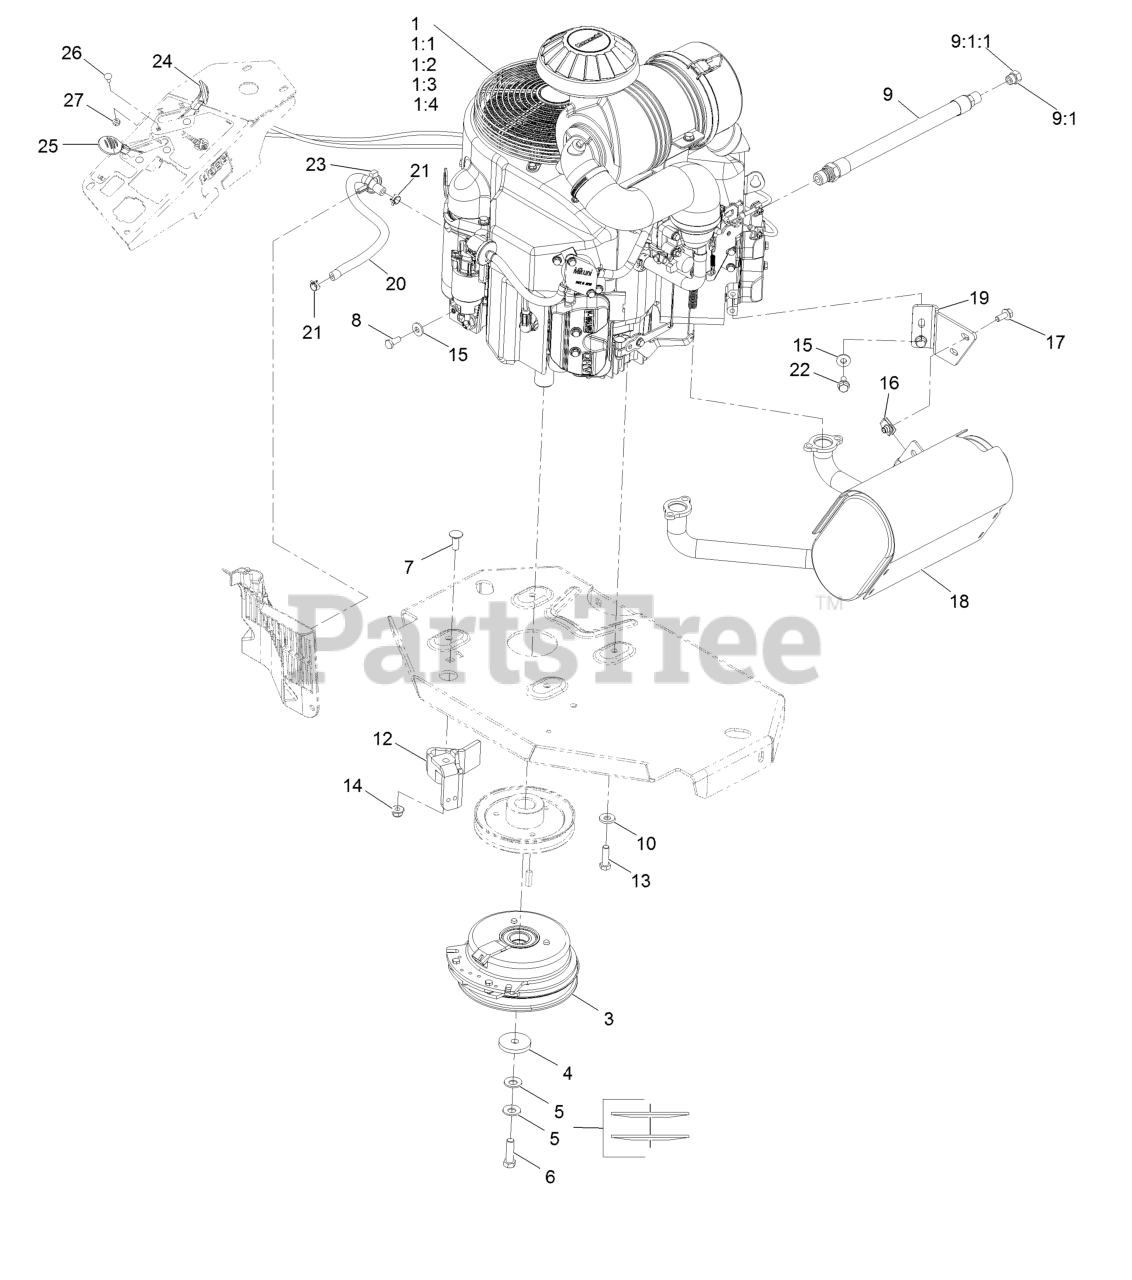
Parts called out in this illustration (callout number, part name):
1:1	Kawasaki 49065-2078 Engine Oil Filter
1:2	Kawasaki 49019-7001 Fuel Filter
1:3	Kawasaki 11013-7039 Safety Filter
1:4	Kawasaki 11013-7038 Air Filter
3	Clutch Kit
4	Washer-Clutch
5	Washer-Spring Disc 7/16
6	Screw-HH 7/16-20 X 1 1/2 W/Loctite
7	Bolt-Carriage 3/8-16 X 1
8	Screw-HH M8-1.25 X 20Mm
9	Asm-Hose Oil Drain W/Plug
9:1	Plug-W/O-Ring
9:1:1	O-Ring
10	Washer-Spring Disc 3/8
12	Clutch-Anchor
13	Screw-HH 3/8-16 X 1 1/4
14	Nut-Nyloc 3/8-16 Flg
15	Washer-Spring Disc 5/16
17	Screw-HH Flg 5/16-18 X 3/4
18	Muffler
19	Bracket-Muffler
20	Hose-Fuel Line 15"
21	Clamp-Hose
22	Screw-HH M8-1.25 X 20Mm
23	Clamp-Hose
24	ASM, Choke Cable
25	ASM,Throttle Cable
26	Bolt-Carriage #10-24 X 1/2
27	Nut-Nyloc #10-24
